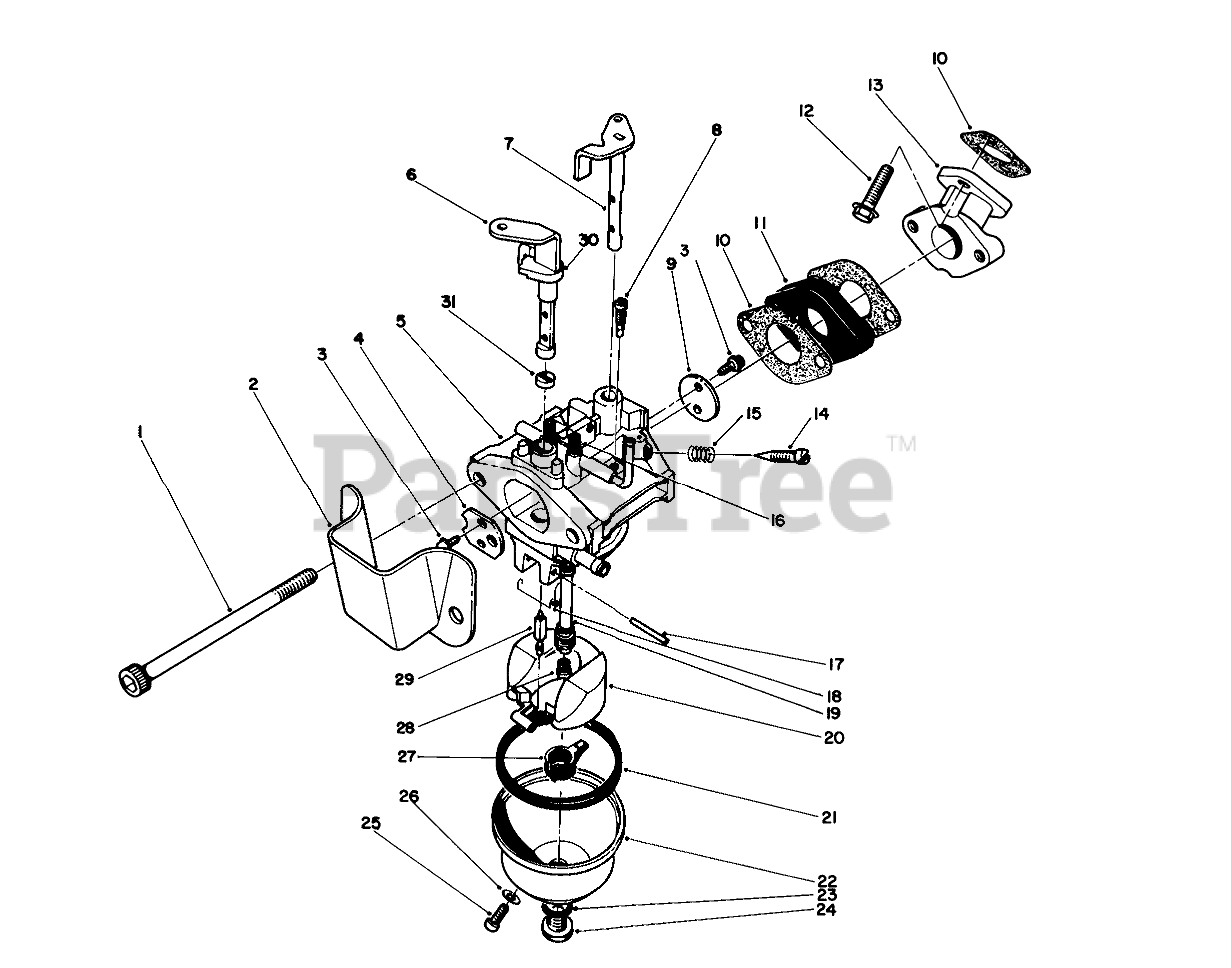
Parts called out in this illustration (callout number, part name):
2	SPIT CUP
3	Screw
4	VALVE
5	Body-Carburetor
6	Shaft-Choke (Incl. Ref. #30 & 31)
7	SHAFT
9	VALVE
10	Gasket-Carburetor
11	CARB INSULATOR
13	MANIFOLD
14	ADJUSTER
15	SPRING-PILOT SCREW
16	SPRING
17	PIN-HINGE
18	TORSION SPRING
19	MAIN NOZZLE
20	FLOAT
21	FLOAT BOWL GASKET
23	GASKET
24	SCREW
25	SCREW
26	GASKET
27	SPACER
28	MAIN JET
29	NEEDLE
30	UPPER CHOKE RING
31	LOWER CHOKE RING
